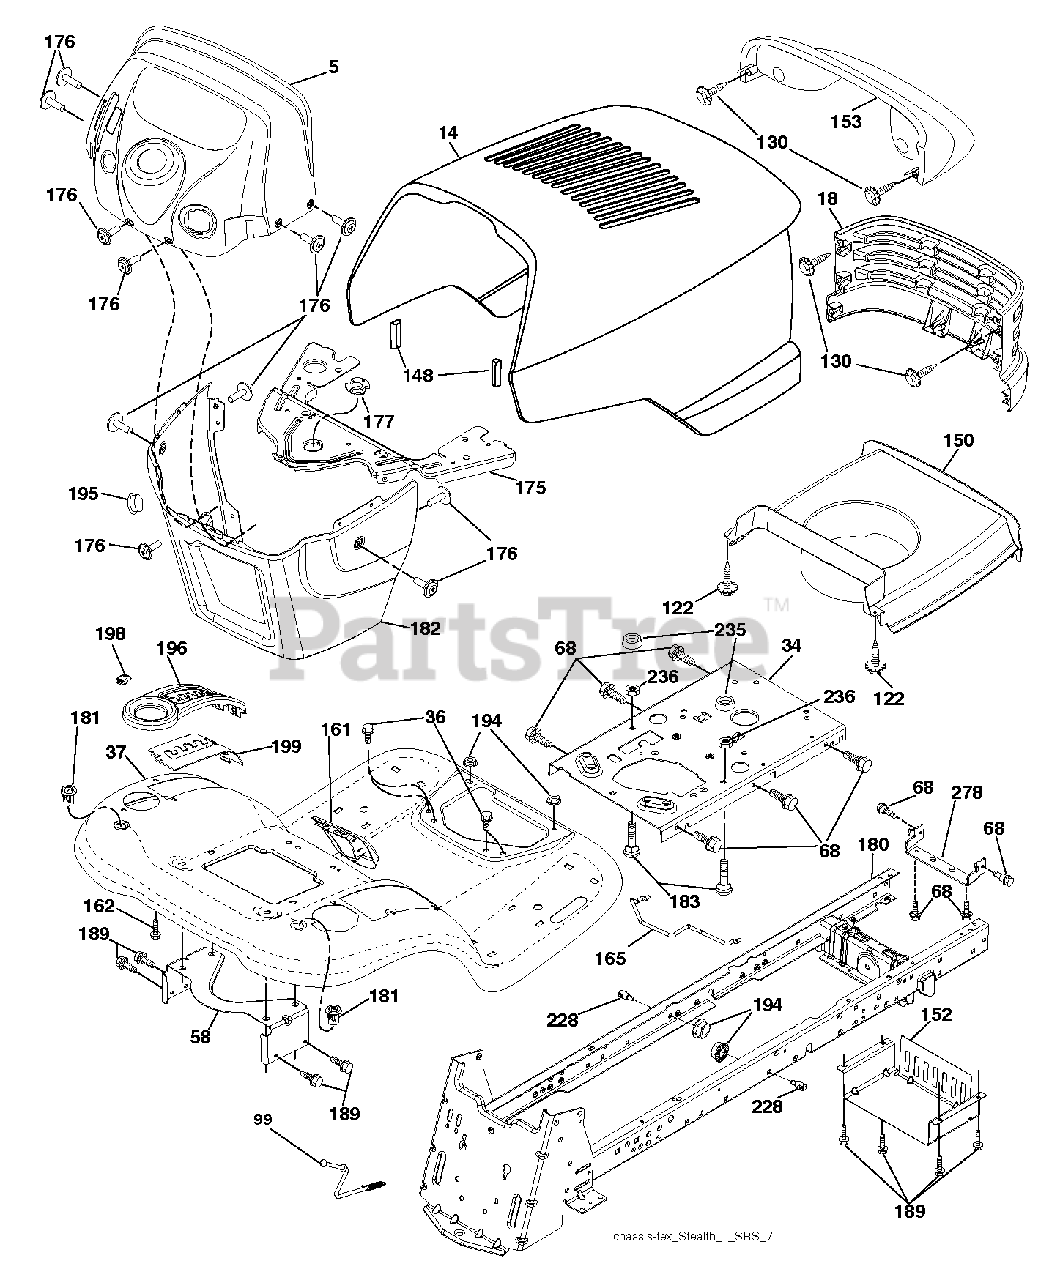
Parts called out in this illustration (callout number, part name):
5	DASH.UPR.STEALTH
34	PLATE.ENGINE.WELDED.CHASSIS
36	SCREW 5/16"
58	BRKT.SUPPORT.FNDR/TANK
68	SCREW LT
99	ROD ASM BYPASS
122	SCREW.WSHD.HEX10-32X5/8
130	SCREW
148	EXTRUSION BUMPER
150	DUCT HOOD
152	SHIELD BROWNING
161	CONSOLE.FUEL.WINDOW.STGT.BLACK
162	SCREW.HI-LO.CONSOLE
165	SUPPORT.TANK.REAR.W/TE
175	CROSSMEMBER.
176	SCREW.#10-24X5/8.RN.QU
177	BUSHING,STEERING
180	CHASSIS.WLDMT.TX.GT.05
181	FEND/FTRST.PCH.CPH.NFW
182	DASH.LOWER.
183	BOLT.5/16-18X1-1/4 FULL.THREAD
189	SCREW
194	NUT LOCK HEX FLANGE 5/16-18
195	PLUG.HOLE.DASH.LOWER.12V.BLK
198	INDICATOR DECK LIFT
199	PLATE DECK LIFT
228	STUD.FASTNER.W/ANTI-ROTATE
235	SPACER FENDER
236	NUT.CENTERLOCK.5/16-
278	BRKT.HOOD/MUFF.STEALTH
